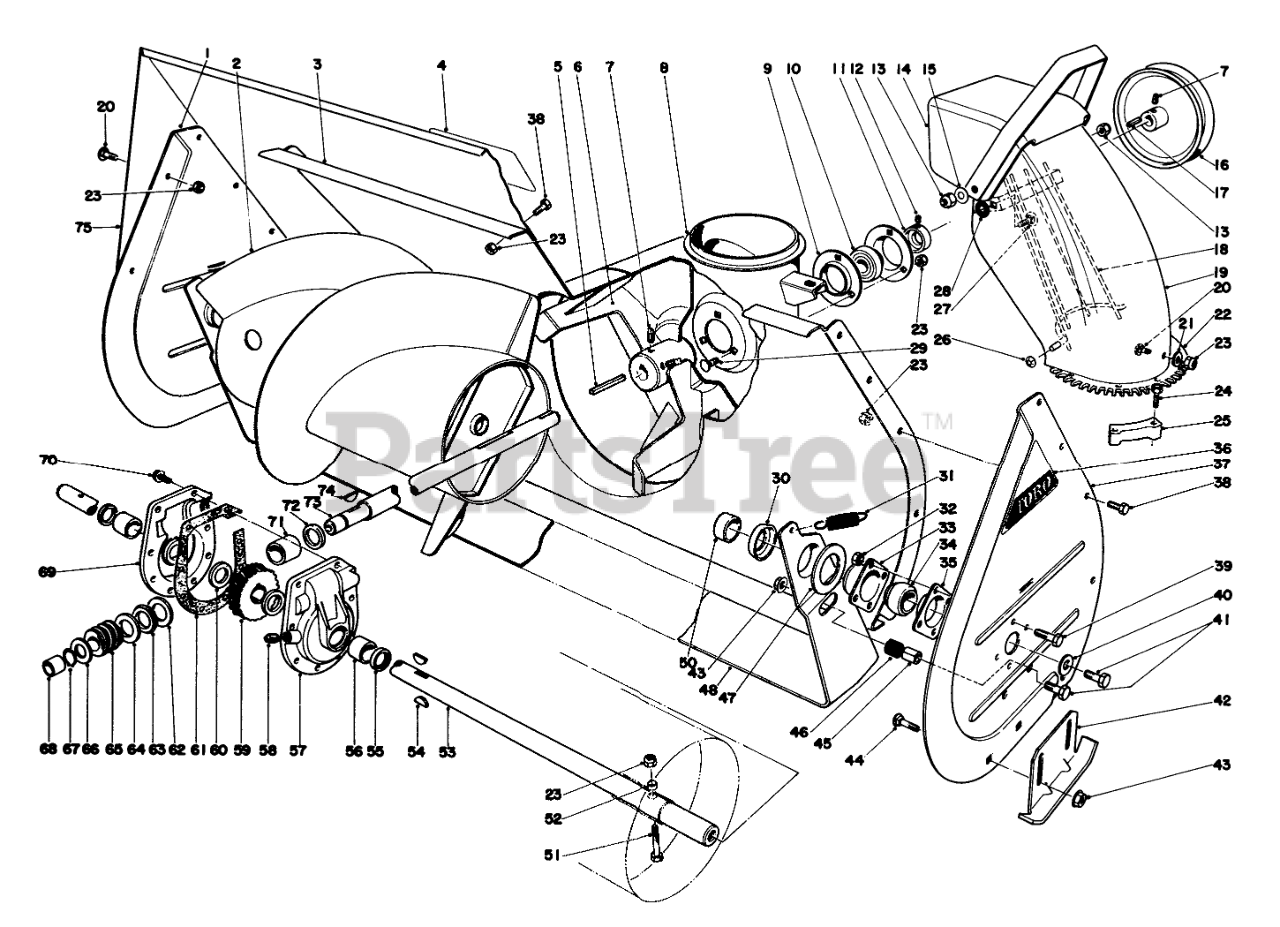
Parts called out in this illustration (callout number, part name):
1	RH AUGER SIDE PLT R
2	RH AUGER WA 26" B
3	Auger Housing
4	Decal
6	IMPELLER ASM
7	SCREW-SET, SQH
8	CHUTE RING
9	BRG FLANGE
10	BALL BRG W/COLLAR
11	EXT LOCKING COLLAR
12	SCREW-HSH
13	NUT-LOCK, CONE
14	Deflector
15	WASHER-BELLEVILLE
16	1/2 X 9.5 DIA PULLEY
17	SQUARE KEY
18	Chute Wire
19	Upper Chute
20	SCREW-CARR
21	WASHER-PLAIN
22	Screw
23	NUT-LOCK, NI
24	SCREW-SPECIAL
25	RETAINER-CHUTE
26	NUT-PUSH
27	SCREW-HH
28	WASHER-RUBBER
29	BOLT-CARR
30	Positioner-Scraper
31	SPRING-TENSION
32	NUT-LOCK, CONE
33	BEARING-FLANGE, FRONT
34	BEARING
35	BEARING-FLANGE, REAR
36	AUGER SIDE PLT DECAL
37	LH AUGER SIDE PLT R
38	SCREW-HH
39	SCREW-HH
40	WASHER
41	SCREW-HH
42	AUGER SKID WA R
43	NUT-HF
44	SCREW-CARR
45	SCRAPER STOP SPACER
46	SCRAPER STOP CUSHION
47	SCRAPER BLADE SPACER
48	SCRAPER BLADE 26 R
50	AUGER SPACER
51	Auger Bolt
52	SPACER-HUB, AUGER
53	26 AUGER SHAFT
54	KEY-WOODRUFF
55	SEAL-OIL
56	BUSHING
57	Gear Case L.H. (Incl. Ref. #55-56)
58	PLUG-PIPE, SQH
59	GEAR-WORM, 27T
60	WASHER-THRUST
61	asket
62	WASHER-THRUST
63	BEARING-THRUST
64	THRUST-WASHER
66	WASHER-THRUST
67	Ring-Snap
68	BUSHING
69	Gear Case R.H. (Incl. Ref. #55-56)
70	SCREW-TAPTITE
71	BUSHING-SPECIAL
72	RING-QUAD
73	SHAFT-IMPELLER
74	KEY-WOODRUFF
75	Auger Extension
